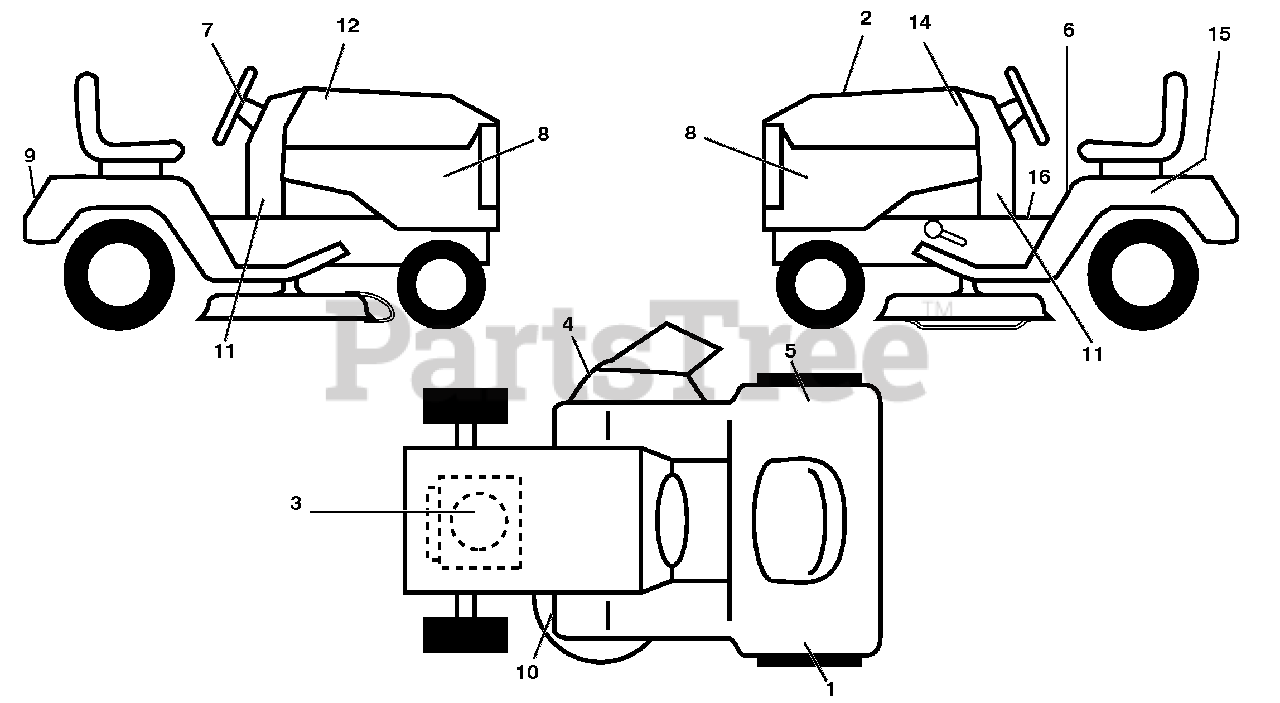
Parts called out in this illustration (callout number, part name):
1	Decal, Fender SDLH
2	Decal, Replacement
3	Decal, Engine HP
4	Decal Warning
5	Decal, Fender SDRH
6	Decal, Fender Danger English
7	Decal Ins Str Wh
8	Decal, Side Panel
9	Decal, Fender
10	Decal, V-Belt Sch.
11	Decal, Lower Dash
12	Decal, Hood RH
14	Decal, Hood LH
15	Decal, Caution, Battery
16	Decal, Oper
16	Decal, Handle Lft Height Adj.
16	Manual, Operator's (E&F)
16	Manual, Parts (E&F)
